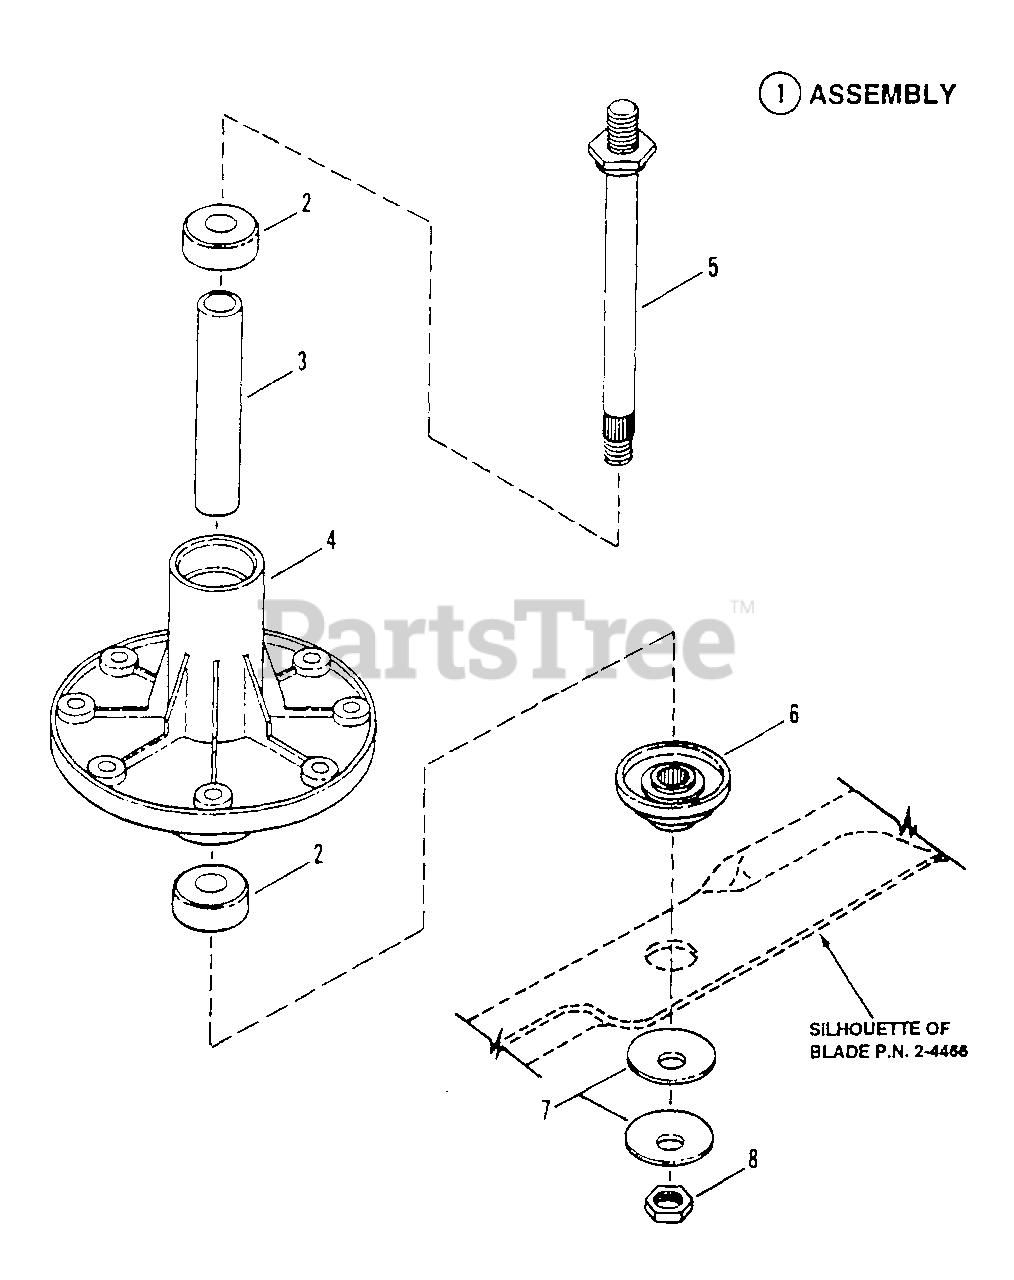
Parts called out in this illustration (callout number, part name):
1	ASSEMBLY, Spindle Housing, 38' Cutting Deck
2	BEARING, Spindle
3	SPACER, Spindle Housing
4	HOUSING, Spindle
5	SPINDLE, (6.899")
6	SPACER, Blade
7	WASHER, Belleville, 19/32 I.D., 1 3/4" O.D.
8	NUT, 9/16-18 Hex Jam
